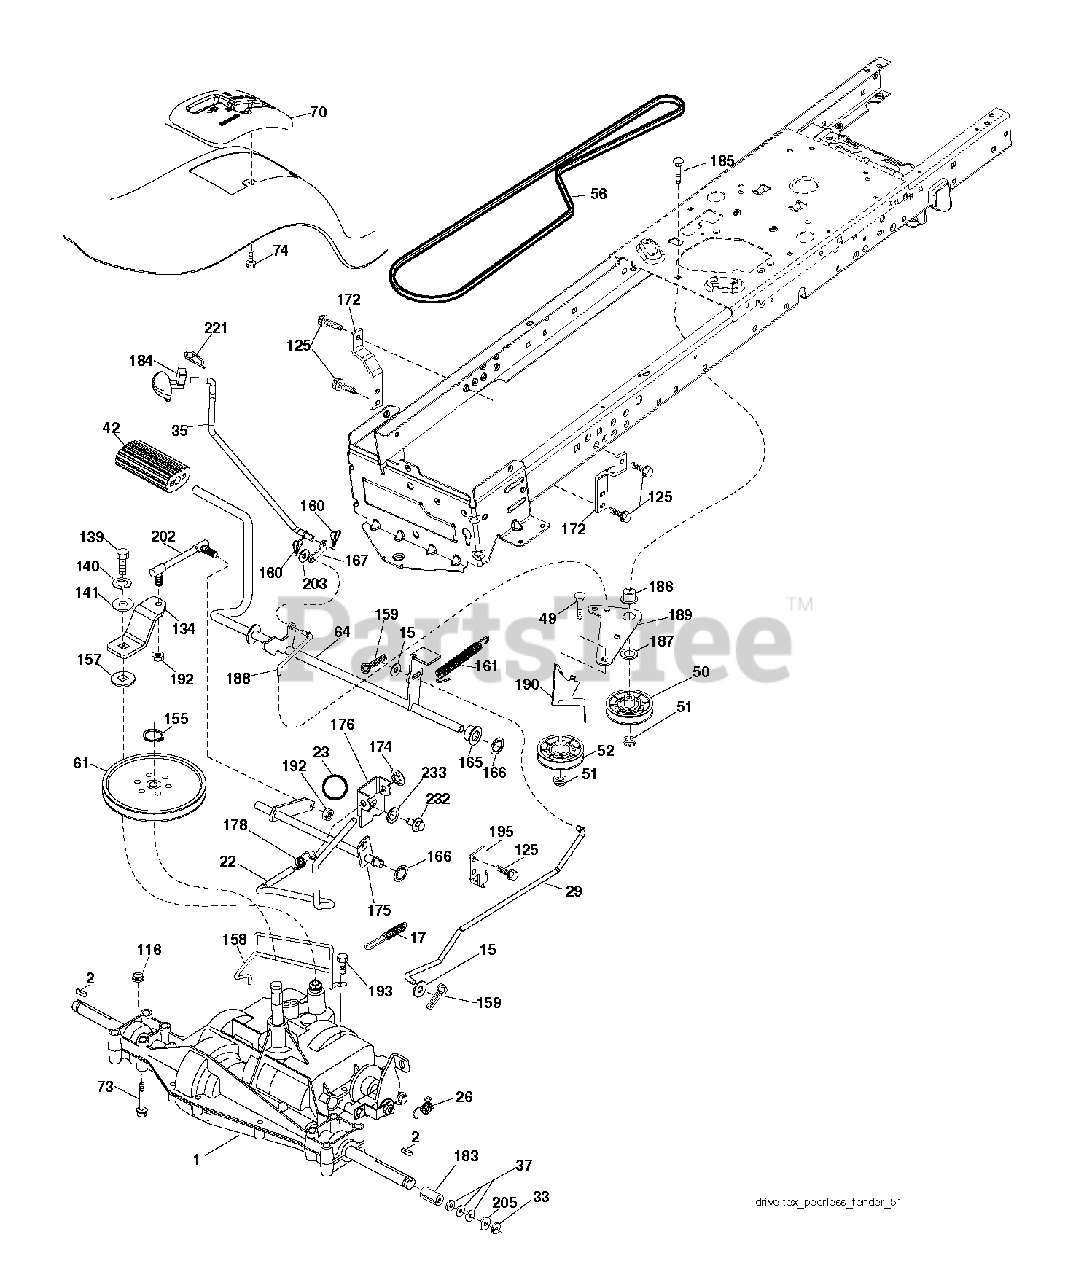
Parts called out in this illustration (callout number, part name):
2	SQUARE KEY
17	SPRING.BRAKE.PEERLESS.TEX
22	ROD.SHIFT.FENDER.TLT.2006
23	KNOB T (1/2-HOLE)
26	SPRING.BRAKE.RTN.GR.DR
29	ROD.BRAKE.PEERLESS
33	E-RING LT
35	ROD.BRAKE.PARKING.LT.T
49	BOLT
50	IDLER.FLAT.910.OFFSET
51	NUT LOCK FLG 3/8-16 UNC
52	IDLER.V-GROOVE.910.OFFSET
56	BELT, V GROUND DRIVE 95 25
64	SHAFT.ASM.PEDAL.BRAKE.
70	CONSOLE.3-SPEED.TEX.BLACK
74	SCREW.HI-LO.CONSOLE
116	NUT LOCK HEX FLANGE 5/16-18
125	SCREW
134	ARM SHIFT
139	Bolt, 1/4-20 unf Grade 8 w/Patch
140	LOCKWASHER
141	WASHER LT
155	RETAINING RING LT
157	WASH-SHFT PLT LT
158	KEEPER.PMS.18/20.D4365
159	COTTER PIN
160	RETAINER CLIP
161	SPRING, RETURN LT
165	BUSHING.SHAFT.BRAKE.HAND
166	NUT.PUSH.625
167	LATCH.BRAKE.SPRING
172	STRAP.TRQ.LH.GEAR.DRIV
174	NUT.PUSH.500.2006
175	SHAFT ASM SHIFT
176	ARM.CLEVIS.ROD.SHIFT
178	SPRING.SHIFT.GT2006
184	HANDLE.PARKING.BRAKE.LTTEX.667
186	SPACER.RETAINER
187	WASHER 12/32X2X10GA
188	LINK.CLUTCH.GROUND.DRIVE
189	BELLCRANK.GROUND.DRIVE.TEX.
190	KEEPER.BELLCRANK.DRIVE
192	NUT LOCK CENTER 1/4 -28 FNTHD
193	SCREW 5/16"
195	BRKT.ROD.BRAKE.PEERLES
202	LINK.SHIFT.PMST.18" (SPG1286)
203	WASHER
221	RETAINER.SPRING.CLIP.H
232	BOLT FIN HEX 7/16-14 X 1
233	WASHER SERRATED
